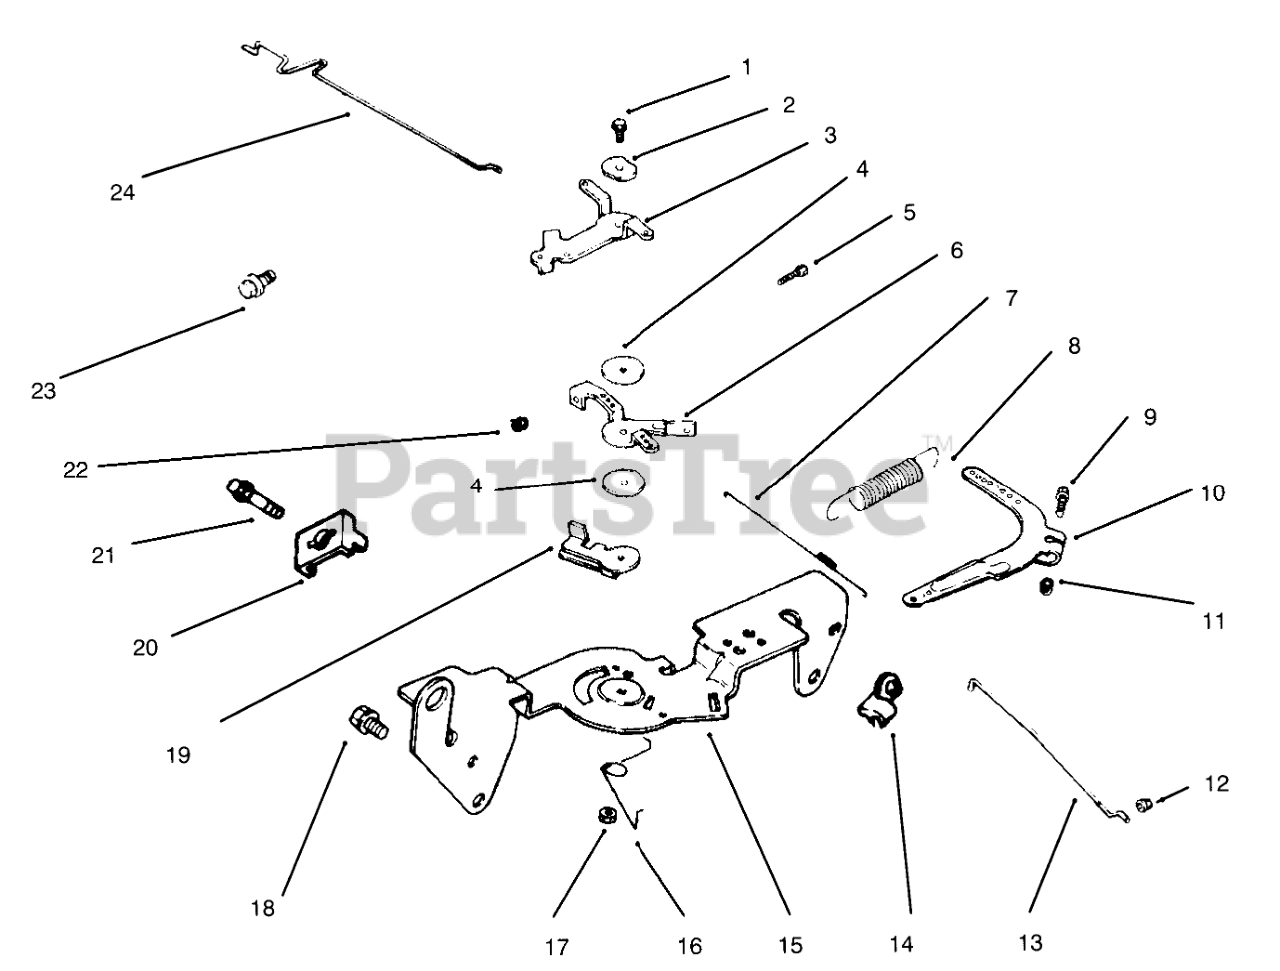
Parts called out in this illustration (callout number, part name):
2	Washer-Wave
3	Lever-Choke
6	Spring-Linkage
7	Lever-Throttle Control
8	Spring-Governor
10	Lever-Governor
12	Bushing
13	Linkage-Throttle
14	Bushing-Linkage
15	Bracket-Control
16	Spring-Choke Return
17	Nut
18	Screw
19	Lever-Throttle Actuator
21	Screw
22	Nut
23	Screw
24	Linkage-Choke
